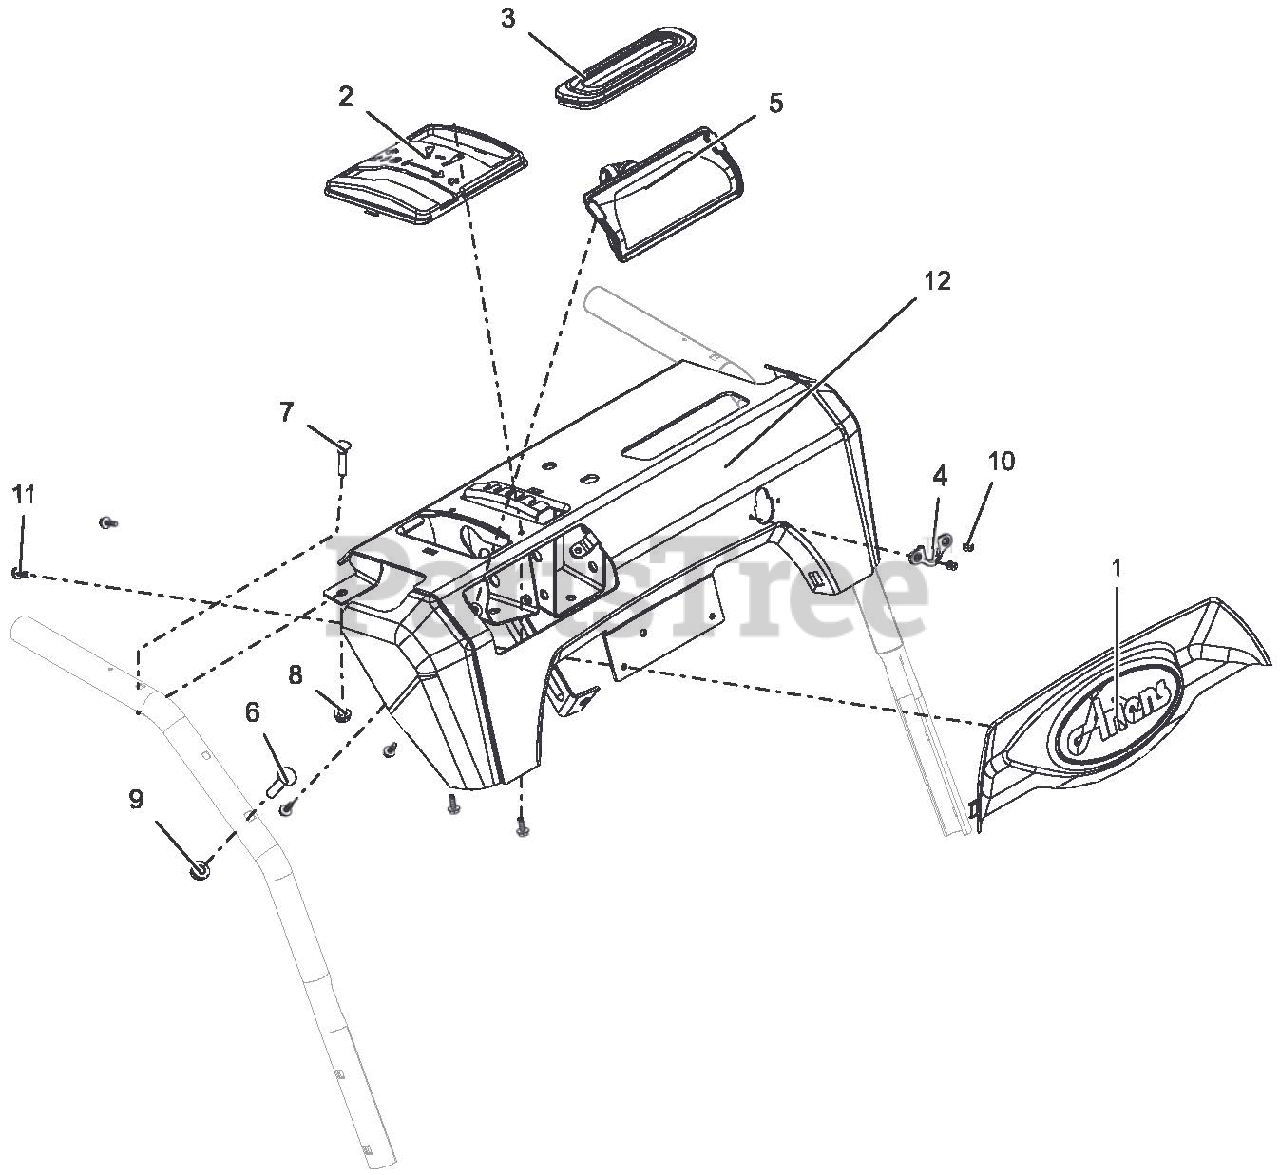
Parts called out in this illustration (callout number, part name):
1	DASH BEZEL, ARIENS LOGO - PRO
2	SHIFT BEZEL W/ NEUTRAL
3	GROMMET, BOOT, QUICK TURN
4	GROMMET, CABLE, QUICK TURN 2
5	HEADLIGHT ASY, HALO 20W 2SHOT
6	@BLT-RDHDSQNK .31-18X1.50 G5YZ
7	BLT-RDHDXLSQNK.25-20X1.25 G5ZC
8	@NUT-LK-CTR-FLG .25-20 YWZC
9	@NUT-LK-TOP-FLG .31-18 YWZC
10	RVT-POP #43 .125X.313 STL ZINC
11	SCR-TAP #10X.50 BOSS INDHXHD
12	KIT, DASH PANEL W/DECAL HYD TK
